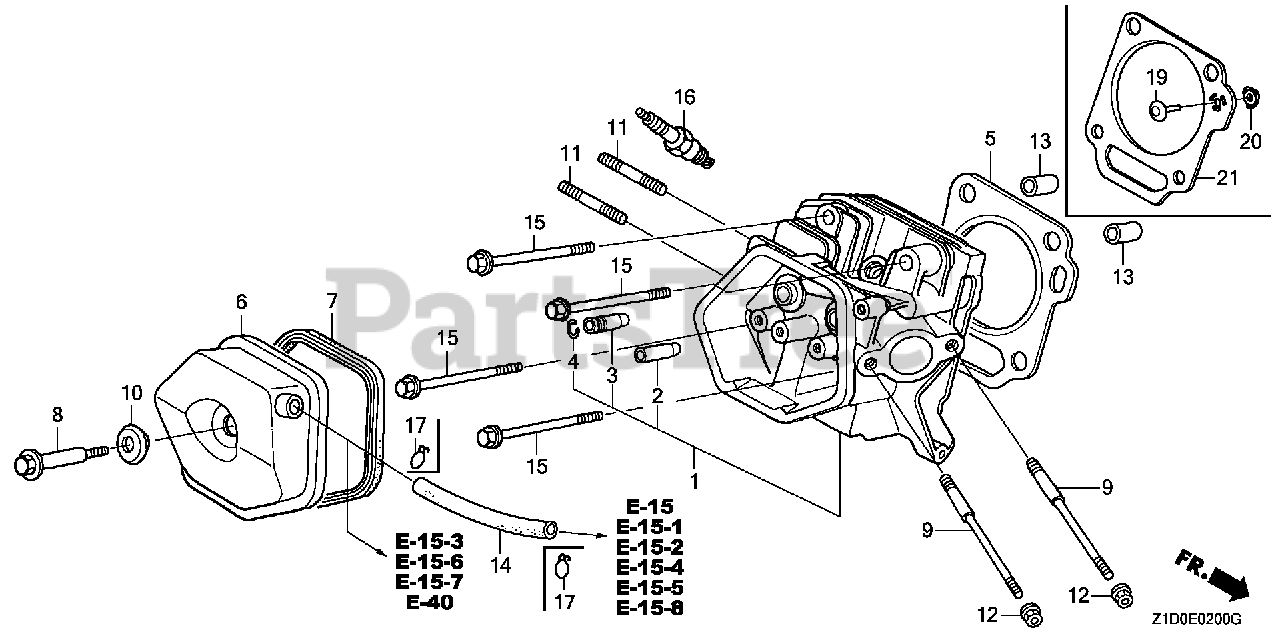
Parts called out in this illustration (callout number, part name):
1	CYLINDER HEAD
2	GUIDE, VALVE (OVER SIZE)
3	GUIDE, EX. VALVE (OVER SIZE)
4	CLIP, VALVE GUIDE
5	GASKET, CYLINDER HEAD
6	COVER, HEAD
7	GASKET, HEAD COVER
8	BOLT, HEAD COVER
9	BOLT, STUD (8X123)
10	WASHER, HEAD COVER
11	BOLT, STUD (8X32)
13	PIN, DOWEL (12X20)
14	TUBE, BREATHER
15	BOLT, FLANGE (10X80)
16	SPARK PLUG (BPR5ES) (NGK)
16	SPARK PLUG (BPR6ES) (NGK)
16	SPARK PLUG (W16EPR-U) (DENSO)
16	SPARK PLUG (W20EPR-U) (DENSO)
